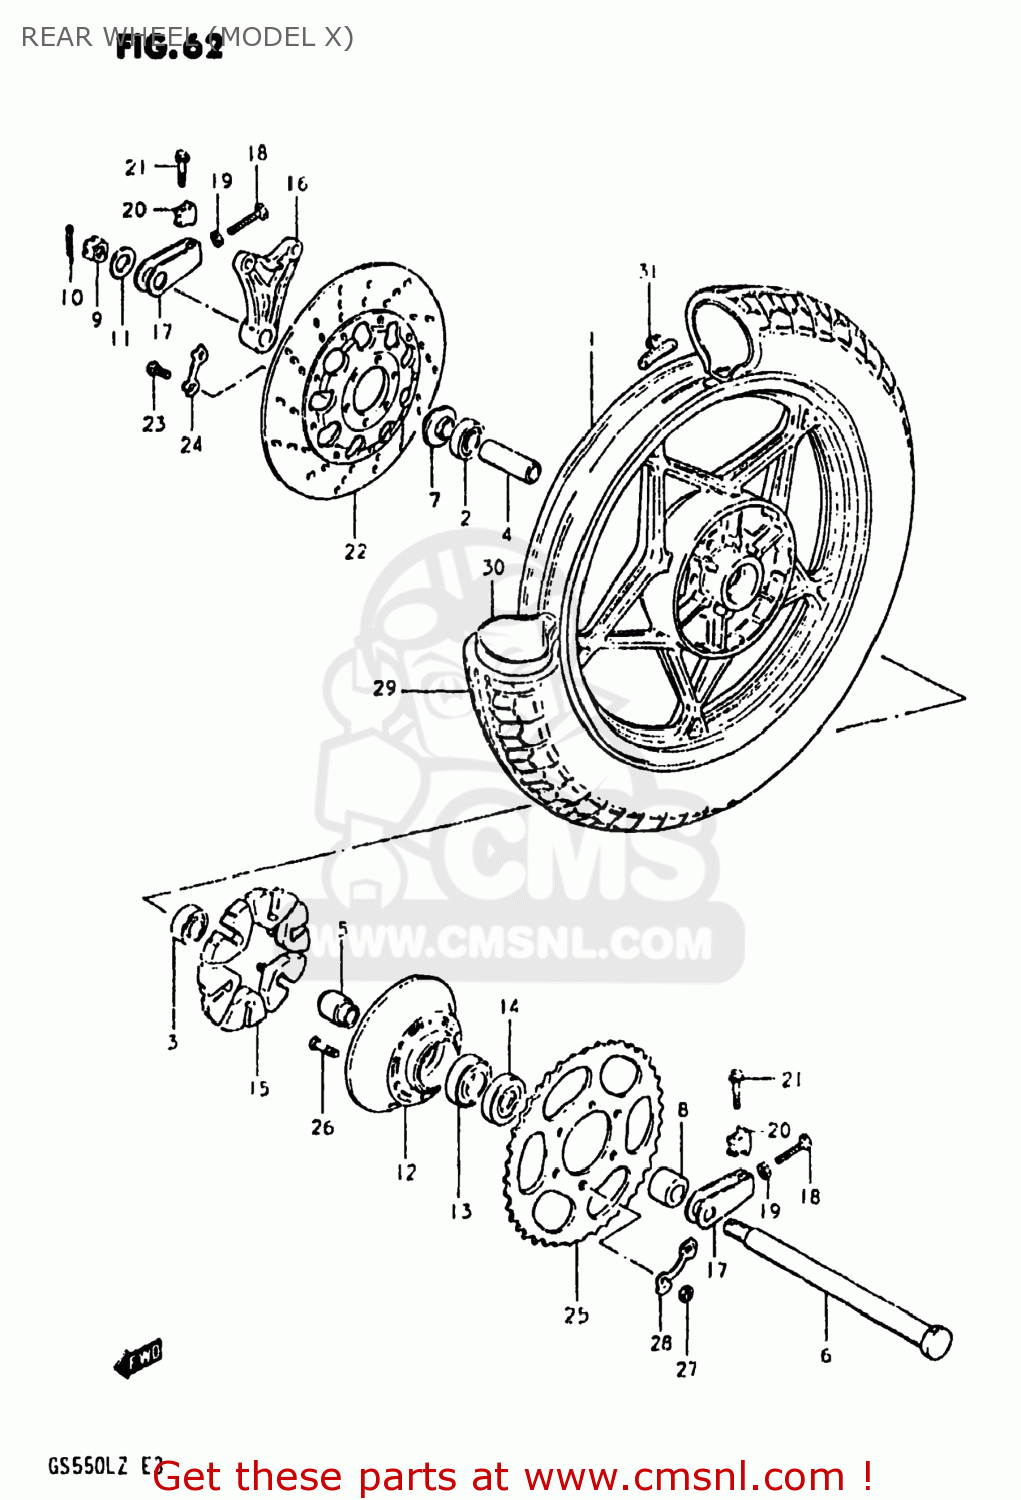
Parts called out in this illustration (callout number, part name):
1	WHEEL,REAR
2	BEARING
3	BEARING
4	SPACER(20.5X28X88)
5	RETAINER,REAR SPROCKET D
6	AXLE,REAR
7	SPACER,REAR AXLE
8	SPACER (17X33X21.1)
9	NUT
10	PIN,COTTER
11	WASHER (17X30X3.2)
12	DRUM,REAR SPROCKET MOUNT
13	BEARING
14	SEAL,OIL(33X62X7)
15	ABSORBER,REAR HUB SHOCK
16	BRACKET,RR,CALIPER
17	ADJUSTER,CHAIN
18	BOLT 8X50
19	NUT
20	SUPPORTER,CHAIN ADJUST
21	BOLT
22	DISC,BRAKE
23	BOLT(8X30)
24	WASHER
25	SPROCKET,REAR (NT:49)
26	BOLT
27	NUT
28	WASHER
29	TIRE
30	TUBE ASSEMBLY,WHEEL,INNER
31	BALANCER,WHEEL
